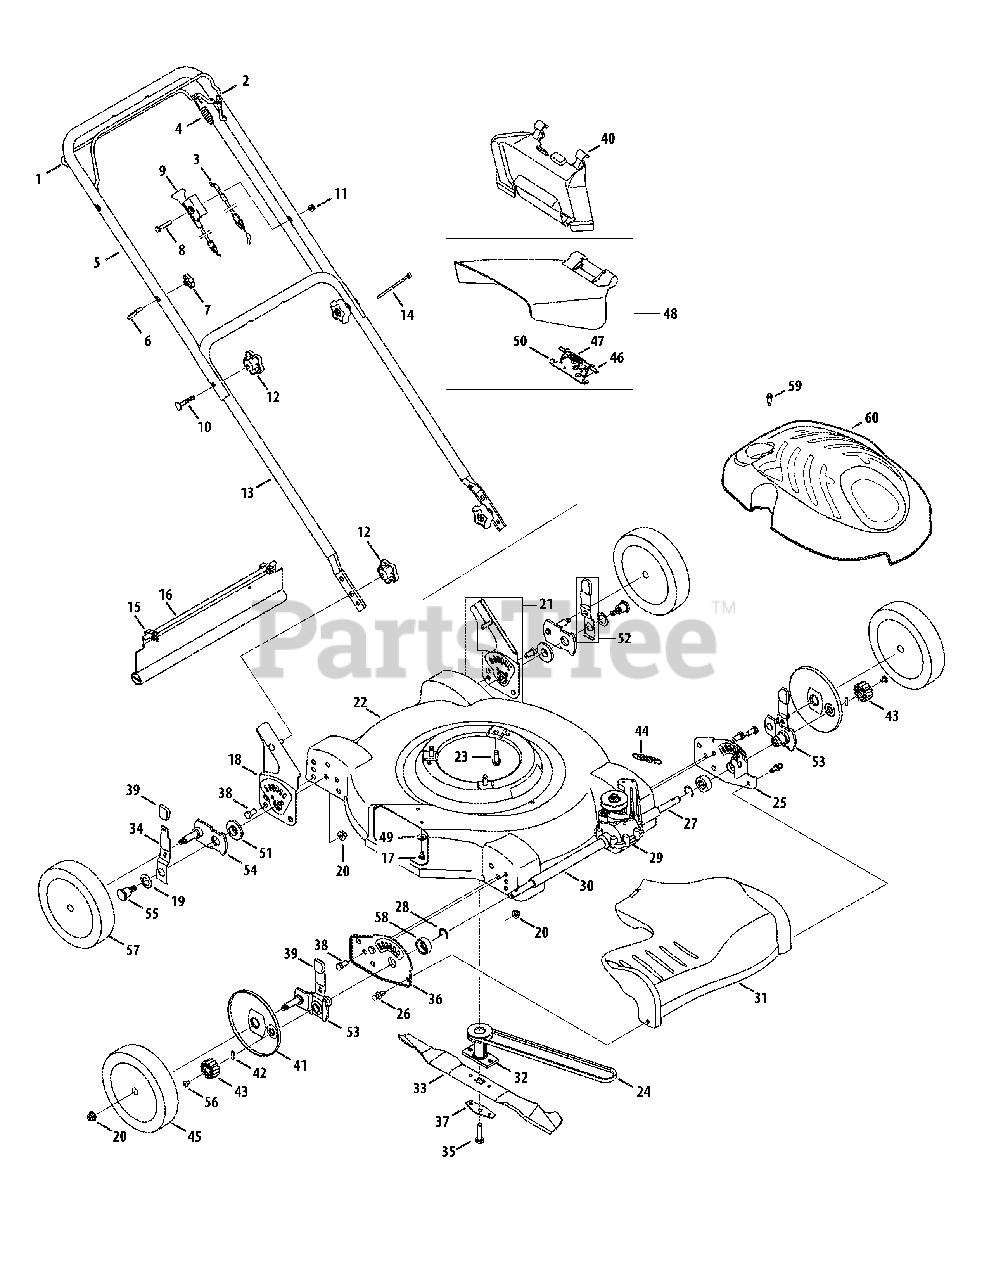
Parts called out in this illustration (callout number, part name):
1	Drive Control
2	Blade Control
3	Blade Control Cable
4	Drive Control Cable
5	Upper Handle
6	Eye Bolt
7	Wing Nut, 1/4-20
8	Hex Screw, 1/4-20 x 1.50
9	Choke Cable
10	Carriage Bolt, 5/16-18 x 2.0
11	Flange Lock Nut, 1/4-20
12	Star Knob
14	Cable Tie
15	Hinge Clip
16	Trail Shield
17	Hex Screw, 1/4-20 x.500
18	Handle Bracket Assy - RH
19	Bell Washer, .760 x 1.25 x.041
20	Lock Nut, 3/8-16
21	Handle Bracket Assembly - LH
22	22" Deck Assembly
23	Hex Washer Scr., 3/8-16 x 1.0
24	V-Belt, 3L x 32.90
25	Forward Height Adj. Plate - LH
26	Rivet
27	Sleeve Spacer, .550 ID x 2.22
28	Retainer Ring
29	Transmission Assy. Comp.
30	Sleeve Spacer, .550 ID x 8.51
31	Transmission Cover
32	Blade Adapter
33	22" Mulching Blade
34	Spring Lever
35	Screw, 3/8-24 x 1.5
36	Forward Hght. Adj. Plate - RH
37	Blade Bell Support
38	Hex Cap Screw, 3/8-16 x.75
39	Adjustment Knob
40	Mulch Plug
41	Wheel Dust Cover
43	Spur Gear 14T - RH
43	Spur Gear 14T - LH
44	Ext. Spring, .47 OD x 2.50
45	Front Wheel
46	Hinge Pin
47	Torsion Spring
48	Side Discharge Assembly
49	Bell Washer, .265 ID x.75 OD
50	Deflector Chute Adapter
51	Height Adjustment Bearing
52	Rear Hgt. Adj. Lever Assembly
53	Front Lever Assembly - RH
53	Front Lever Assembly - LH
54	Rear Pivot Arm Assembly
55	Shoulder Screw, 3/8-16
56	Screw, 1/4-20 x .390
57	Rear Wheel
58	Bearing Support Spacer
59	Screw, #12-16 x 1.00
60	Engine Shroud
